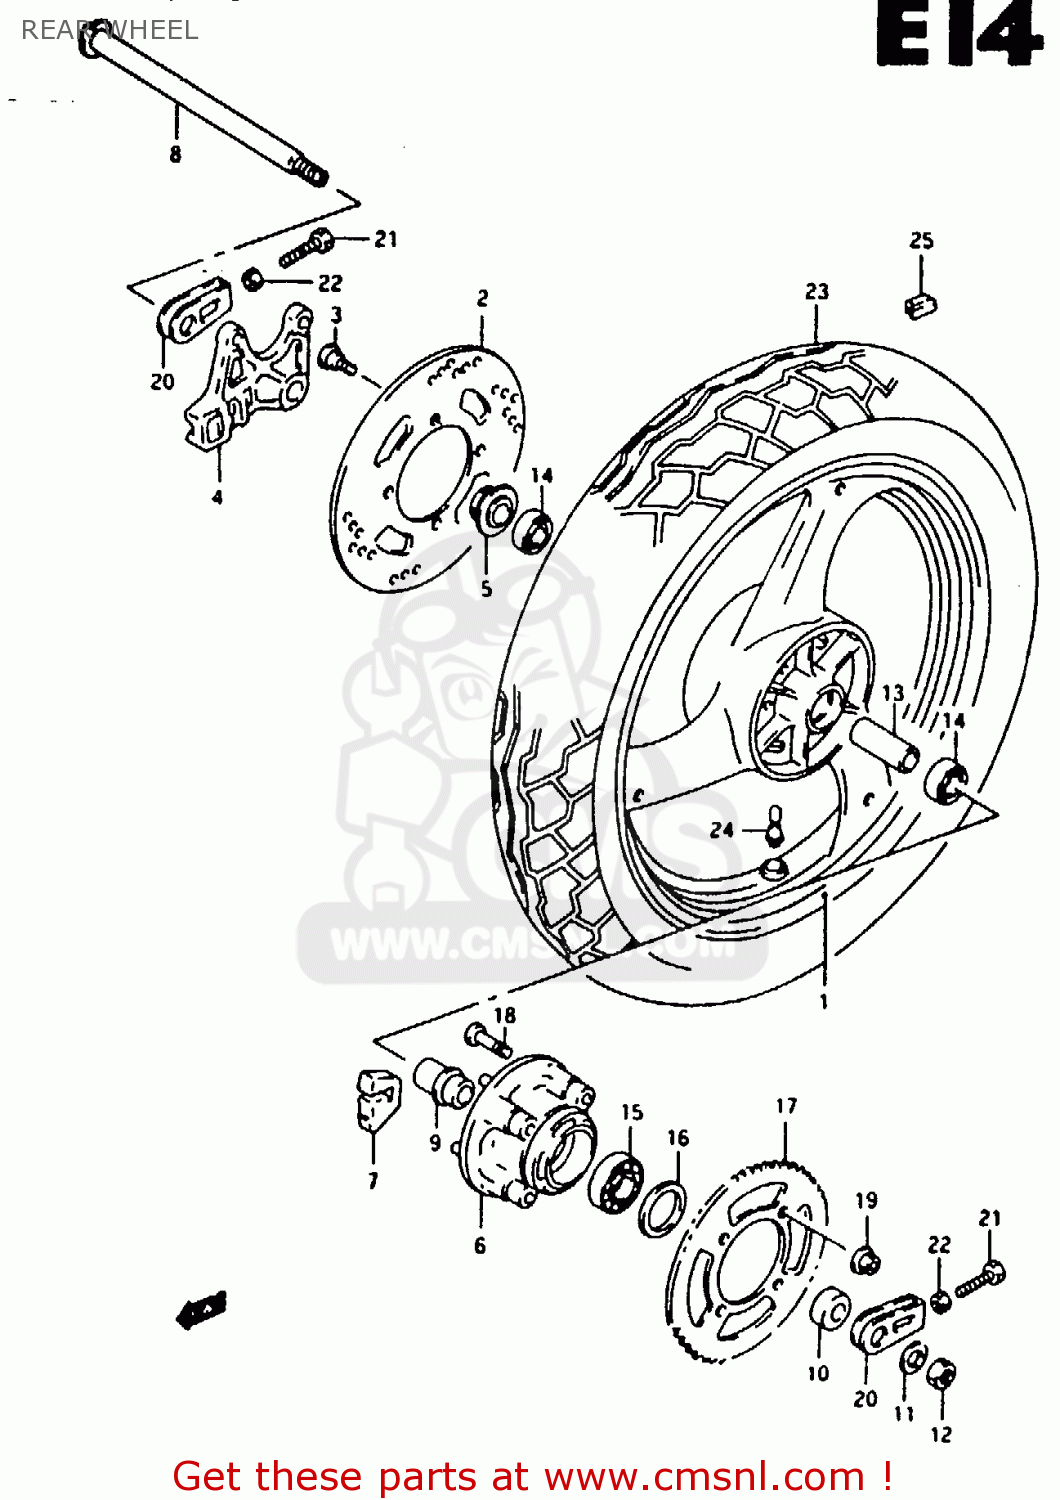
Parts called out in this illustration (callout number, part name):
1	WHEEL, REAR (17*MT2.75) GRAY
2	DISC,RR BRAKE
3	BOLT,BRAKE DISC
4	BRACKET,RR CALIPER
5	SPACER,RR AXLE,L
6	DRUM,RR SPROCKET MOUNTING
7	ABSORBER,RR HUB SHOCK
8	AXLE, REAR
9	RETAINER,RR SPROCKET DRUM
10	SPACER(17X34X16.5)
11	WASHER(17X30X3)
12	NUT 16MM
13	SPACER(17.5X25X81)
14	BEARING
15	BEARING(25X52X15)
16	SEAL,OIL(34X52X6)
17	SPROCKET, REAR (NT:47)
18	BOLT(10X47)
19	NUT
20	ADJUSTER,CHAIN
21	BOLT(8X49)
22	NUT
23	TIRE, REAR (120/80-17 615) (CUNLOP)
24	VALVE ASSEMBLY,WHEEL,TR412
25	BALANCER,WHEEL
